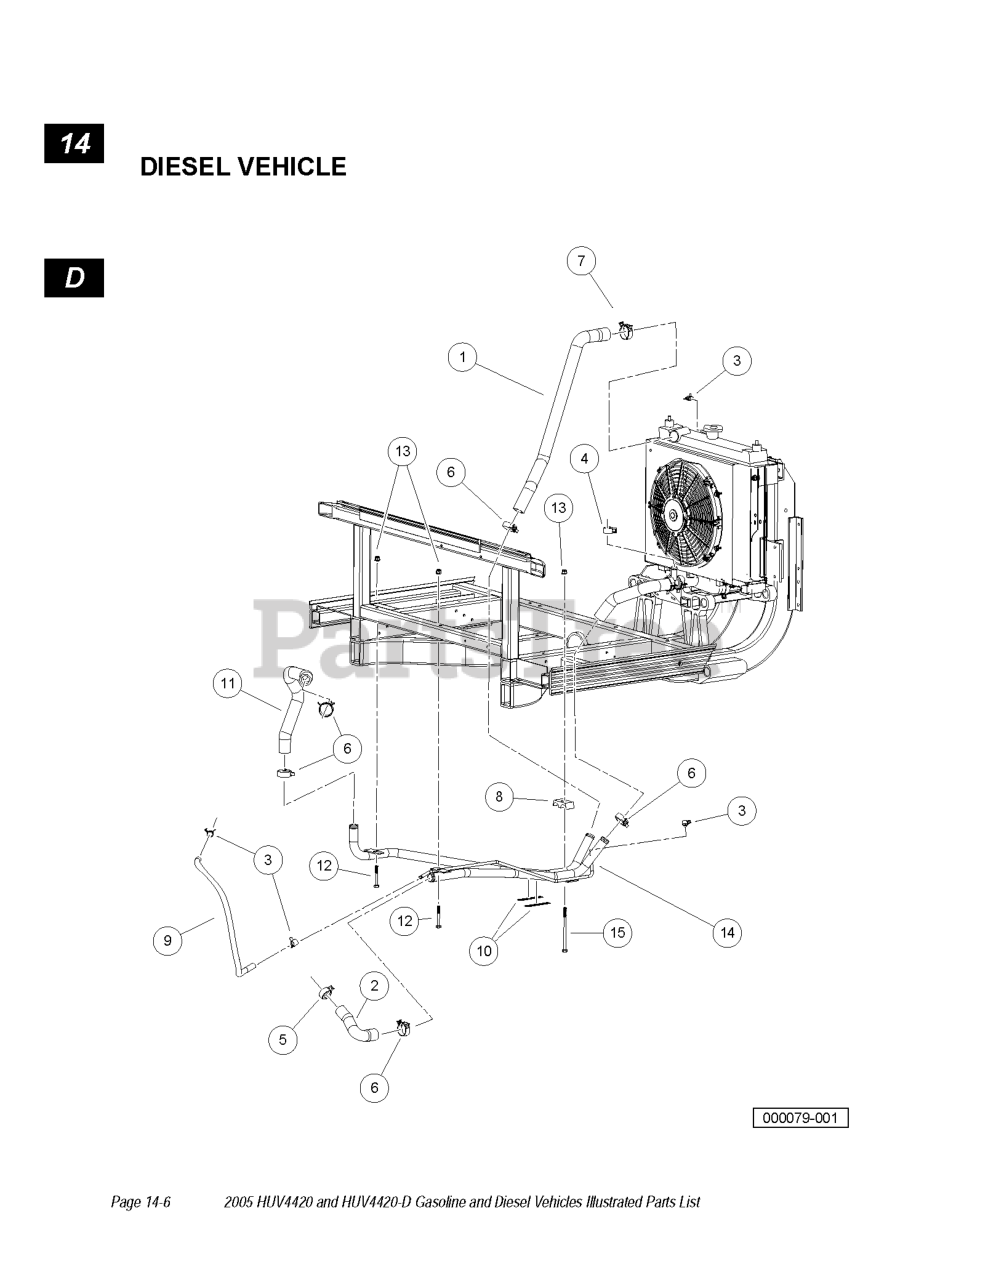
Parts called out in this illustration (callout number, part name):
1	HOSE, COOLANT UPPER RAD
2	HOSE, COOLANT LOWER ENG
3	CLAMP, HOSE, CTB 15MM
4	CLAMP, HOSE, CTB 22MM
5	CLAMP, HOSE, CTB 30MM
6	CLAMP, HOSE, CTB 35MM
7	CLAMP, HOSE, CTB 38MM
8	CLAMP, BAR
9	HOSE, VENT TUBE TO ENG, COOLNT
10	DECAL, WARNING HOT SURFACE
11	HOSE, COOLANT, RETURN, ENGINE
12	BOLT FLG, M8X1.25X65
13	LOCK NUT, FLG M8 X 1.25 NYLON
14	WELDMENT-GROUP-COOLANT PIPE
20	BOLT, M8 X 1.25 X 130
